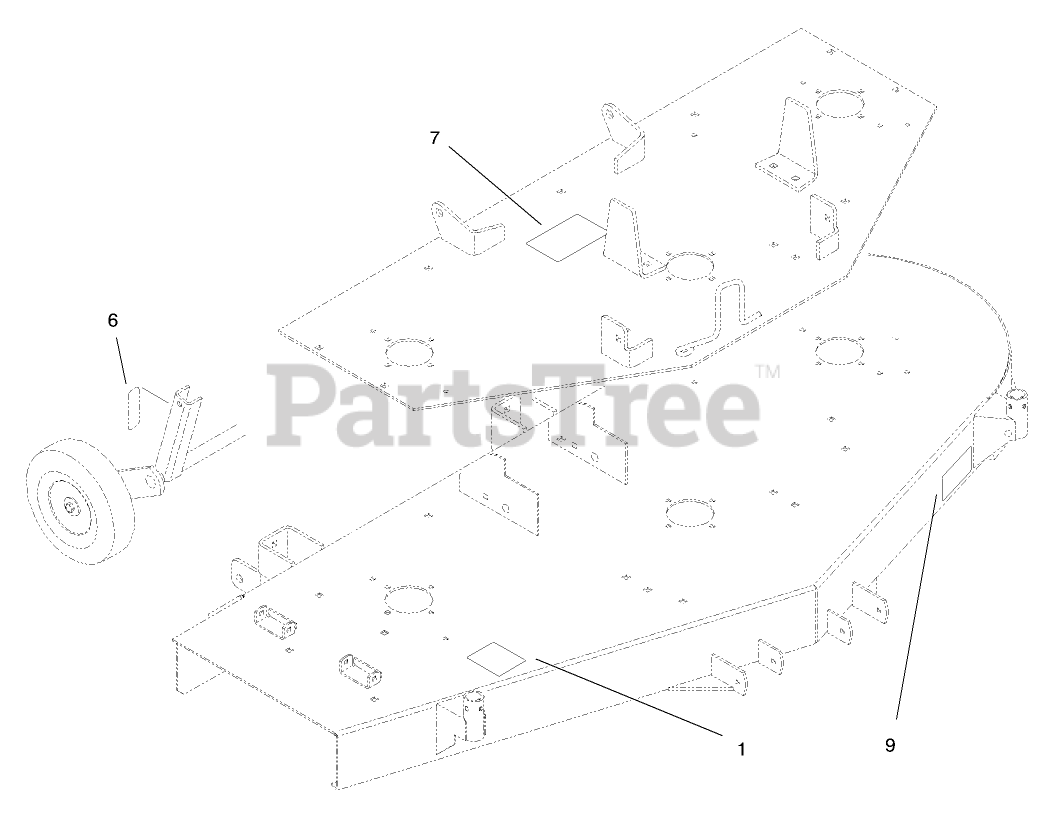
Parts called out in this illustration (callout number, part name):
1	DECAL-BELT ROUTING
6	DECAL-HOC
7	DECAL-BELT ROUTING
9	DECAL-ADJUSTMENT, WHEEL
